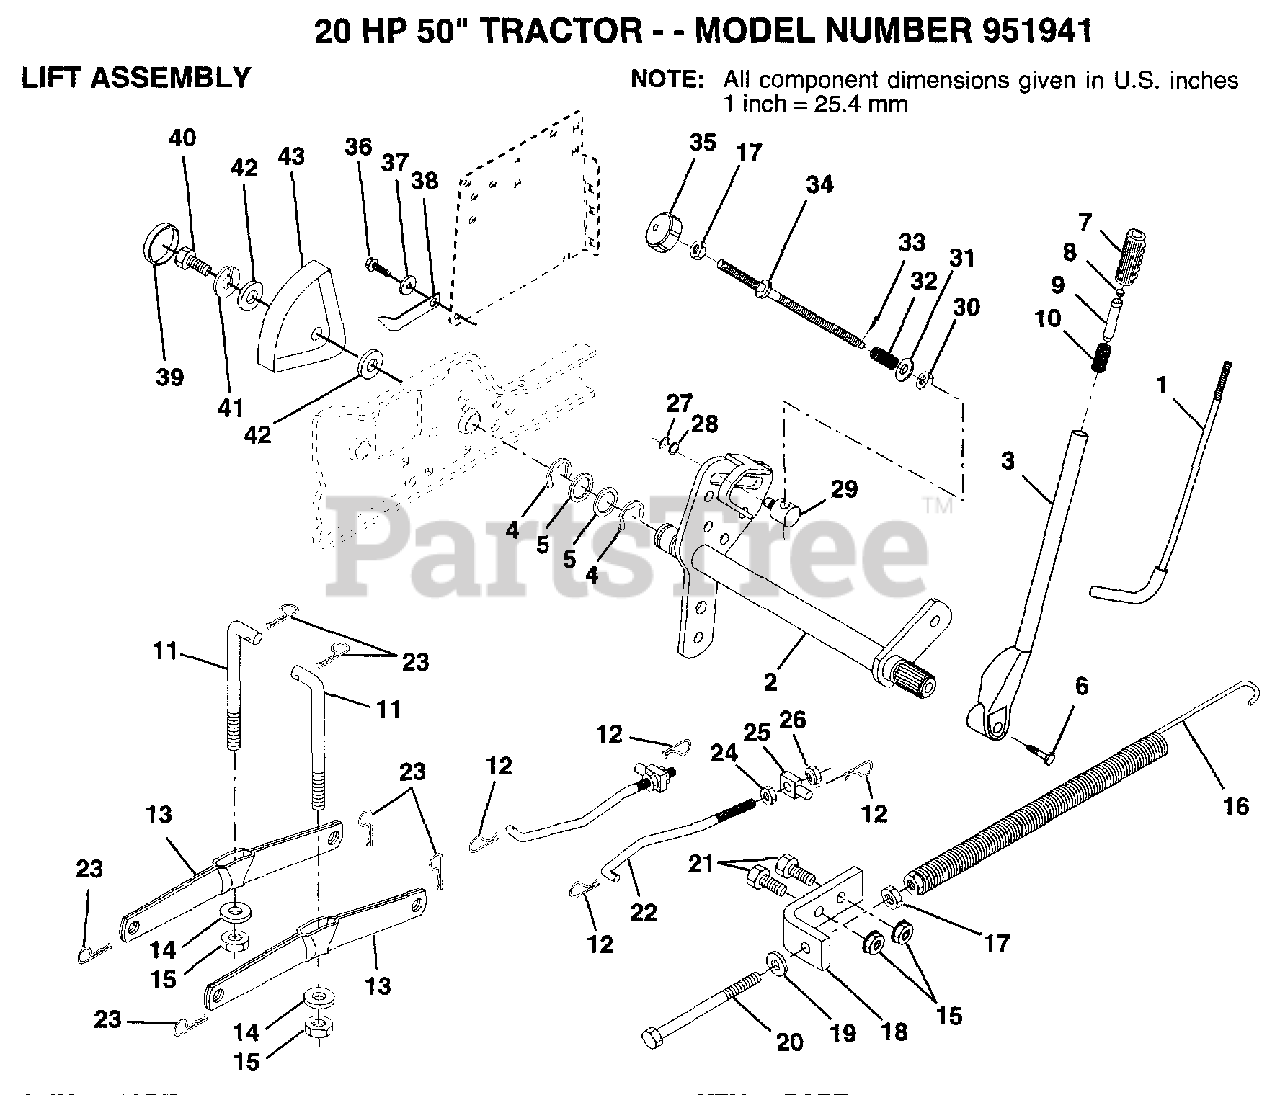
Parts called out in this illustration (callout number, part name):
1	LEVER ROD LT
4	E-RING
5	WASHER
6	"BOLT,HEX"
7	GRIP HANDLE
10	SPRING T
12	RETAINER.SPRING
14	BEARING PVT LH
15	NUT
17	NUT
18	BRACKET SPRING AS
19	WASHER
20	BOLT-ADJ SPRING T
21	BOLT
22	LINK.FRONT
24	NUT
25	TRUNION
26	NUT.LK.W/WSH.1/2.
27	KLIP RING
28	WASHER
29	TRUNION LT
30	NUT T
31	WASHER
32	SPRING.COMP.INF.H
34	ROD.ADJ.LIFT
35	KNOB INF 3/8-16
36	SCREW
37	WASHER T
38	POINTER HGT IND
39	"PLUG,HOLE"
41	LOCKWASHER
42	WASHER
43	HEIGHT INDICATOR
